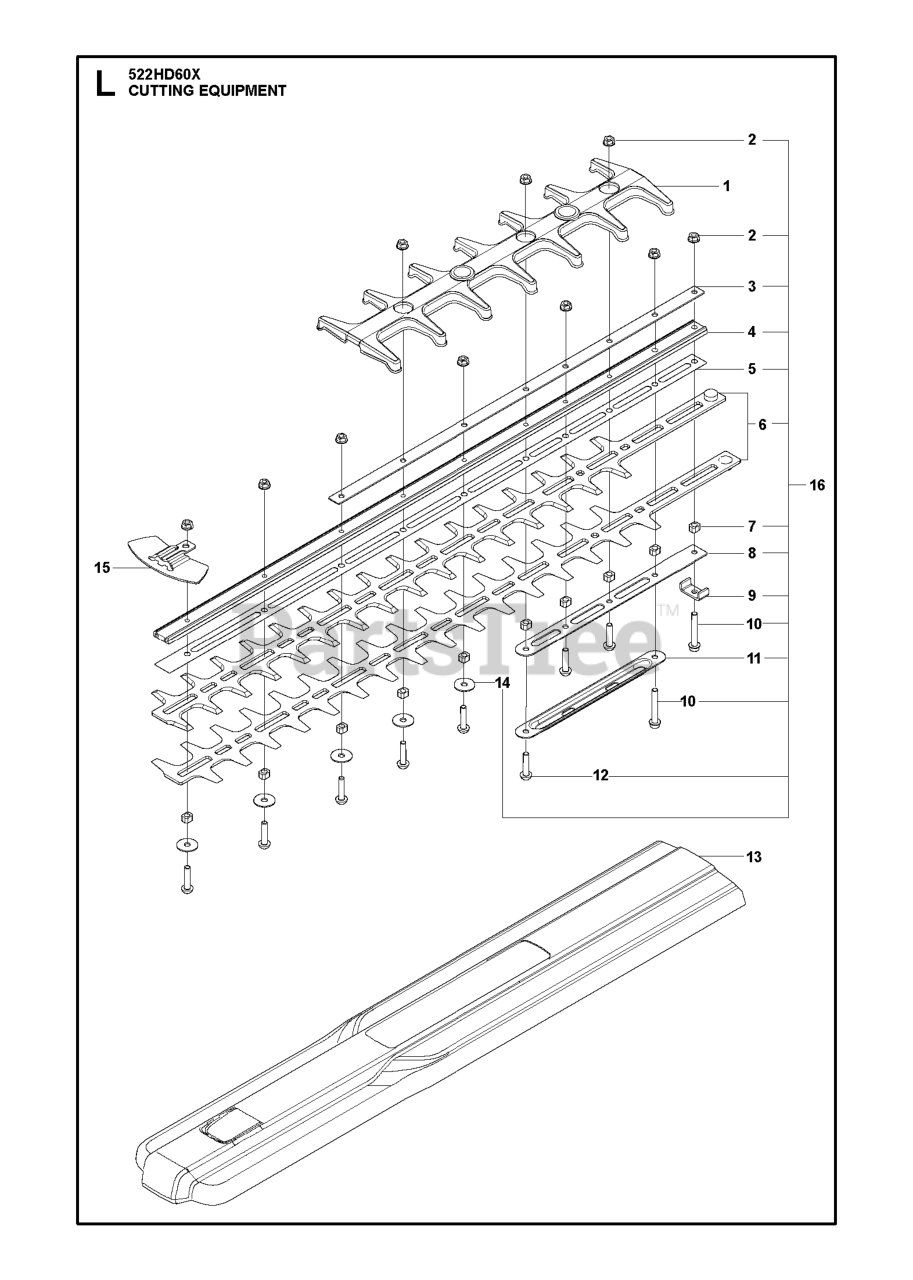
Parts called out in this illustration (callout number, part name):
1	Protection
2	NUT HEXAGON LOCK WITH FLANGE M
3	BAR PLATE UPPER
4	GUIDE BAR HD/HS60
5	WEAR PLATE
6	BLADE KIT HD60
7	SPACER CUTTING DECK
8	BAR PLATE LOWER
11	BAR PLATE LOWER
12	SCREW HEXALOBULAR SOCKET BUTTO
13	TRANSPORT GUARD HUSQVARNA GRE
14	WASHER PLAIN 5.5X19X1.2 ST TBO
15	PROTECTION BLADE TIP
16	CUTTING DECK KIT HD60
